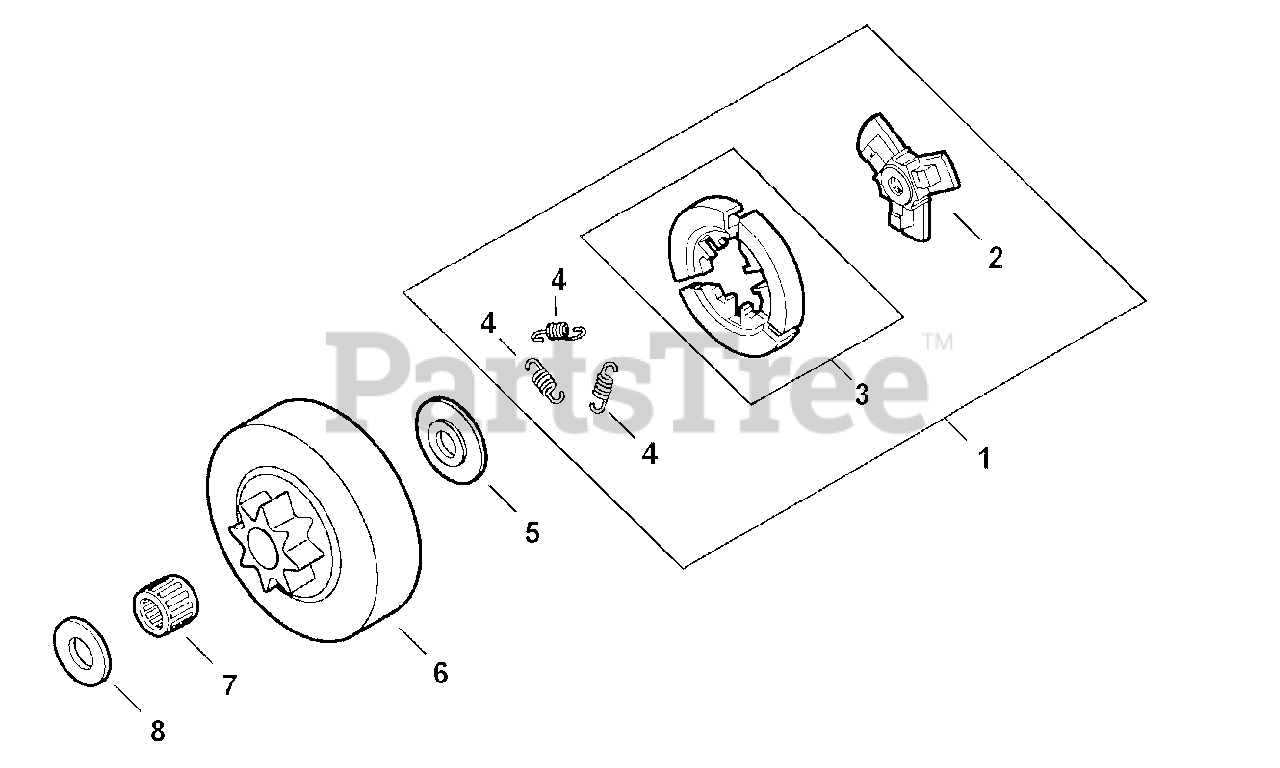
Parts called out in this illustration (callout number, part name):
1	CLUTCH ASSY
2	HUB, CLUTCH
3	CLUTCH SHOE SET
4	SPRING, CLUTCH
5	PLATE, CLUTCH
6	DRUM, CLUTCH
7	BEARING, NEEDLE
